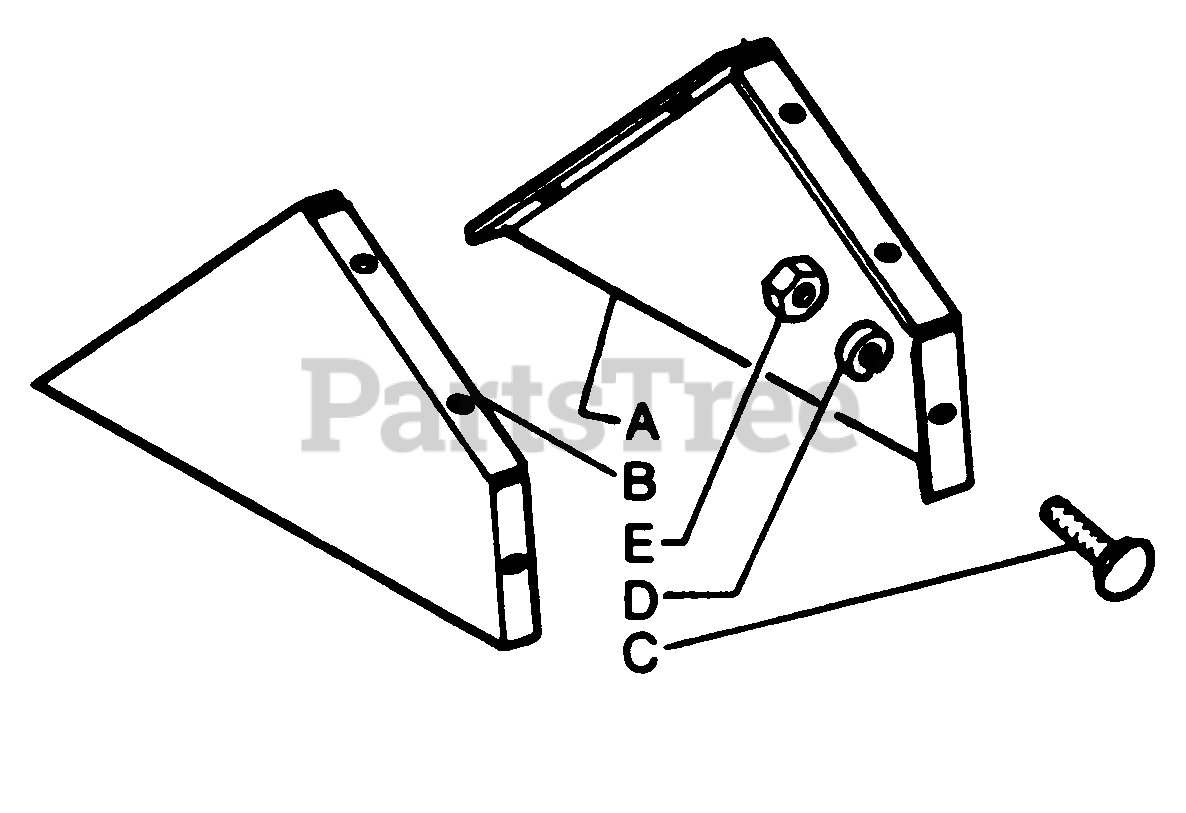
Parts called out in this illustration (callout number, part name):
1	FOOT, right hand
2	FOOT, left hand
3	GUARD, FOOT POCKET, right hand
4	GUARD, FOOT POCKET, left hand
5	FRAME, FRONT PANEL
6	BRACE, FRONT PANEL FRAME
7	SUPPORT, CHUTE CONTROL CRANK
8	BRACKET, REAR ATTACHING, right hand
9	BRACKET, REAR ATTACHING, left hand
10	PLATE, REAR ATTACHING
11	CROSS BAR, REAR
12	POST, FRONT, right hand (straight w/screw)
13	POST, FRONT, left hand (straight w/screw)
14	BRACE, TOP, right hand
15	BRACE, TOP, left hand
16	TOP FRAME, HTS
17	POST, REAR CORNER, right hand
18	POST, REAR CORNER, left hand
19	"L" BRACKET
20	3/4" LOOP
21	FRONT PANEL VINYL
22	WINDSHIELD
23	DOOR, right hand
24	DOOR, left hand
25	REAR CURTAIN
26	TOP, FIBERGLASS, HTS (trim)
27	CRANK, CHUTE CONTROL
28	PARTS BAG (contents listed below)
29	1/4"-20 LOCKNUT
30	DOOR HINGE
31	1/4"-20 x 3/4" BOLT
32	SPRING, DOOR LATCH
33	1/4" FLAT WASHER
34	5/16"-18 x 1-1/2" BOLT
35	3/8"-16 LOCKNUT
36	3/8"-16 x 3/4" BOLT
A	Tine Shield Side-R.H.
B	Tine Shield Side-L.H.
C	Carriage Bolt, 1/4-20 x 5/8 Plated
D	Lock Washer, 1/4 Plated
E	Nut, 1/4-20 Hex, Plated
